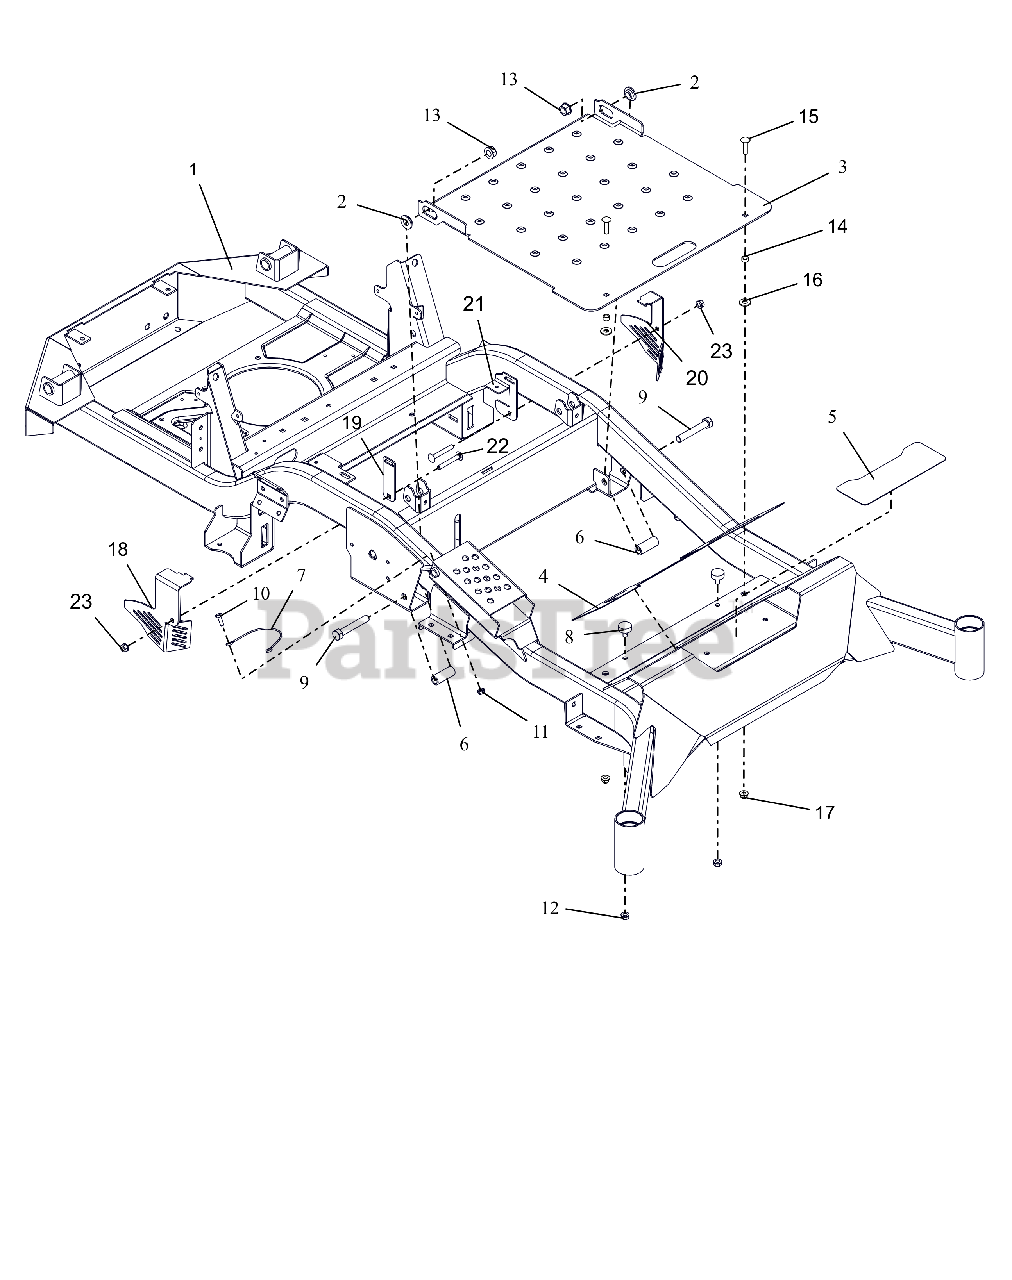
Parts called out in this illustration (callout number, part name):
1	APEX 60"FRAME W/SAFTETY DECALS
2	BSHG-FLG .515X.750X.395X1.120
3	PANEL, ACCESS
4	GRIP, FRONT
5	GRIP, STEP
6	SPACER, .515X.75X1.83
7	CABLE, 12.0 LANYARD, NYLON
8	BUMPER, RUBBER
9	BLT, HEX .50-13X3.00 G5 ZCC
10	BLT, HEX .25-20X.75 G5 ZCC
11	NUT,NYL-FLG .25-20 GF ZCC
12	NUT,SPNLK-FLG .31-18 G5 ZCC
13	NUT-LK-TOP-FLG .500-13 GF ZCC
14	BSHG-SLV .344 X .500 X .260
15	BLT, RHSSN.31-18X1.25 G5 ZCC
16	WSHR,FLT .375X.875X.083 ZCC
17	NUT,LK-NYL-FLG .31-18 G5ZC120
18	GUARD, TRANSAXLE FAN - RH
19	BRKT, TRANSAXLE FAN GUARD
20	BRKT, TRANSAXLE FAN GUARD-LH
21	MOUNT, TRANSAXLE GUARD
22	BLT, RHSSN.31-18X2.25 G5 ZCC
23	NUT,LK-CTR-FLG .31-18 GF ZCC
